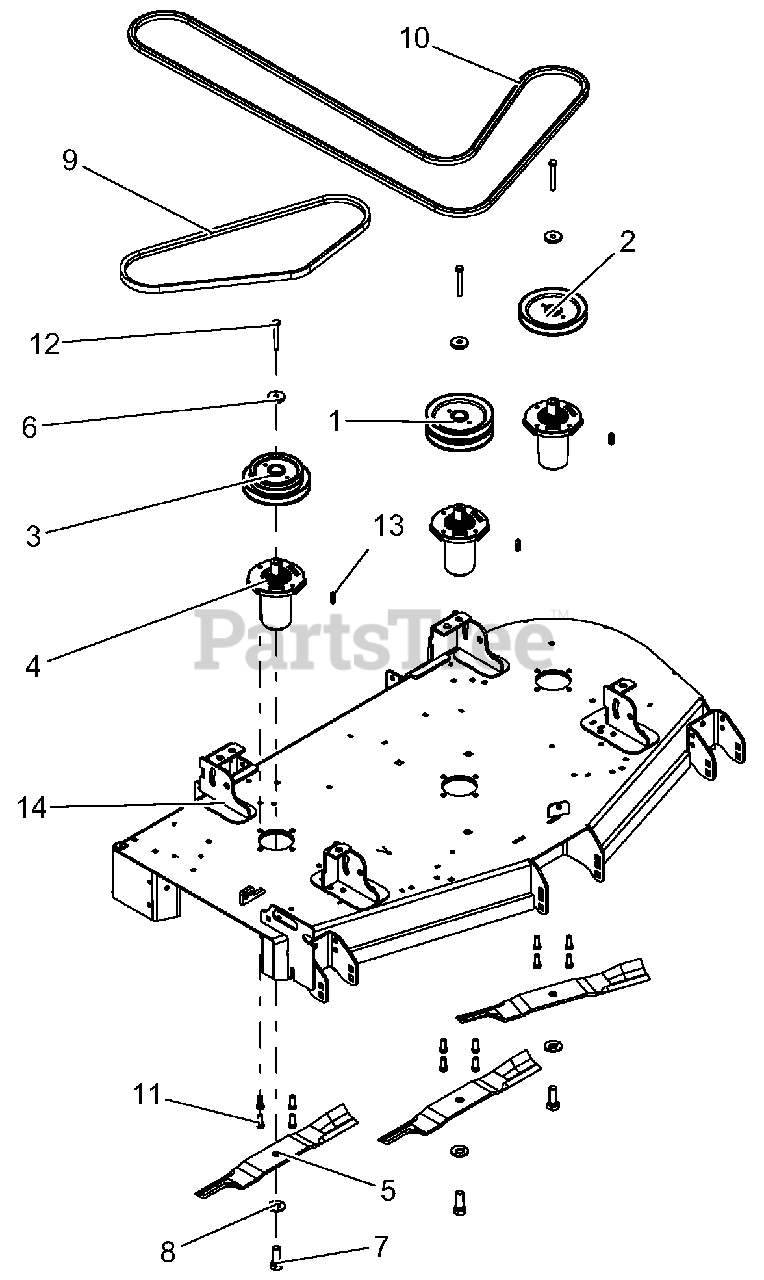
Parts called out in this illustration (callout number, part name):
1	PULLEY, DOUBLE -1" ID X 6.00" OD-BLACK
2	PULLEY, SINGLE -1" ID X 6.00" OD-BLACK
3	PULLEY, DOUBLE -1" ID X 6.00" & 4.75" OD
4	SERVICE, ASM SPINDLE- DUCTILE
5	BLADE, 18.00" MOVER (HI-LIFT)
6	RETAINER, SHEAVE SPINDLE
7	BLT, HEX .62-18X1.75 GR8 YWZC
8	WSHR, BLVL .63X1.625X.14
9	BELT, B 56.00 RAW COGGED
10	BELT, BB 118.00 WRAPPED HEX
11	BLT-HEX .38-16X1.00 GR5 YWZC EP30
12	BLT-HEX .38-16X2.75 GR8 YWZC
13	KEY-SQ .250X.250X1.00 RC 40-50
14	WLDMT, 52" PT200 SIDE DISCHARGE DECK-RED
